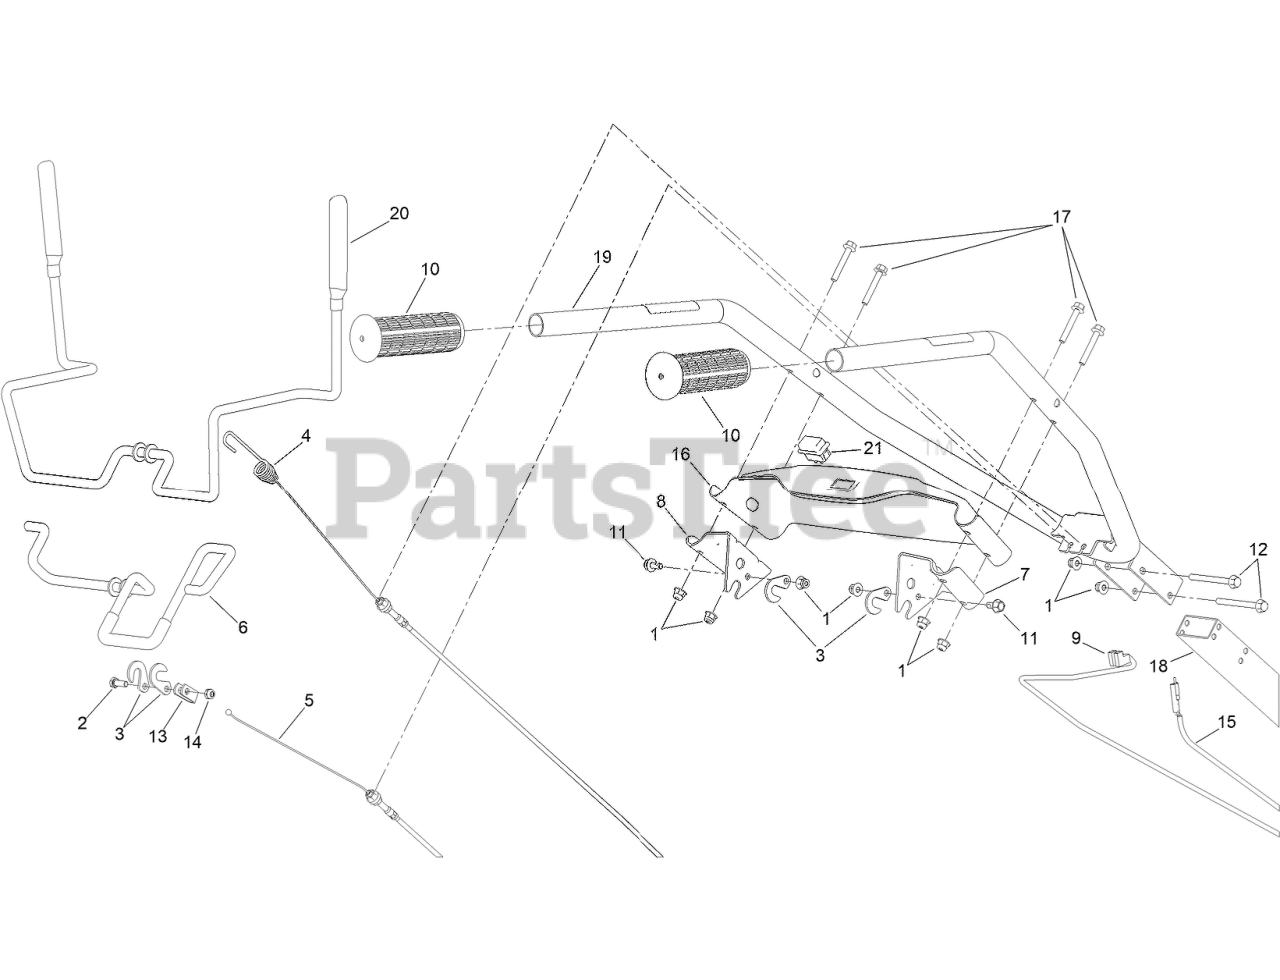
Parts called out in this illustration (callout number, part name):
1	NUT-HEX
2	SCREW-HHCS
4	CABLE-FORWARD
5	CABLE-REVERSE
6	BAIL-REVERSE
7	BAIL-RIGHT
8	BAIL- LEFT
9	HARNESS-WIRING
11	SCREW-HF
12	SCREW-HF
13	YOKE-REVERSE BAIL
14	NUT-HEX
15	WIRING HARNESS-ENGINE
16	DASH-TILLER
17	SCREW-HHF
19	HANDLEBAR
20	LEVER-FORWARD
21	SWITCH
